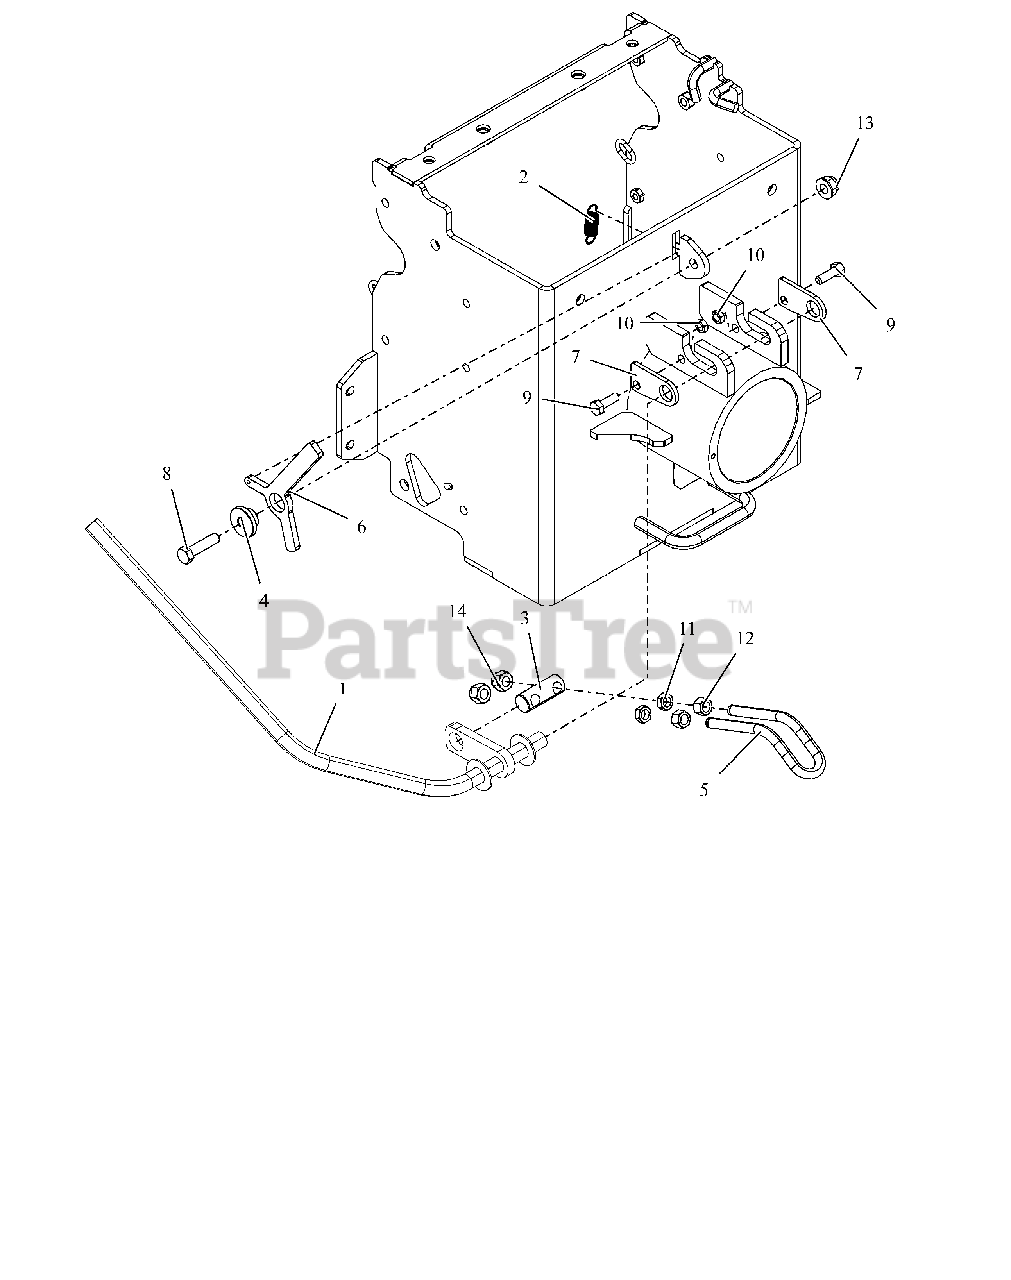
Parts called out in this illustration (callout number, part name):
1	WLDMT, LEVER ATTACHMENT
2	SG-TENS .041X.500X1.750
3	ROD, PIVOT
4	BSHG, STEP .413X.776X1.25X.413
5	LATCH, BOW
6	LOCK, HANDLE
7	PLATE, LOCK LEVER
8	BLT, HEX M10-1.5 X 40 G8.8 ZCC
9	BLT, HEX M8-1.25X25 G8.8 ZCC
10	NUT,NYL M8-1.25 G8.8 ZCC
11	NUT, HEX-JAM M10-1.5 A2-35 SS
12	NUT, HEX M10-1.5 A2CL70 SS
13	NUT,NYL-FLG M10-1.5 G8.8 ZCC
14	NUT, LK-NYL M10-1.5 A2CL70 SS
